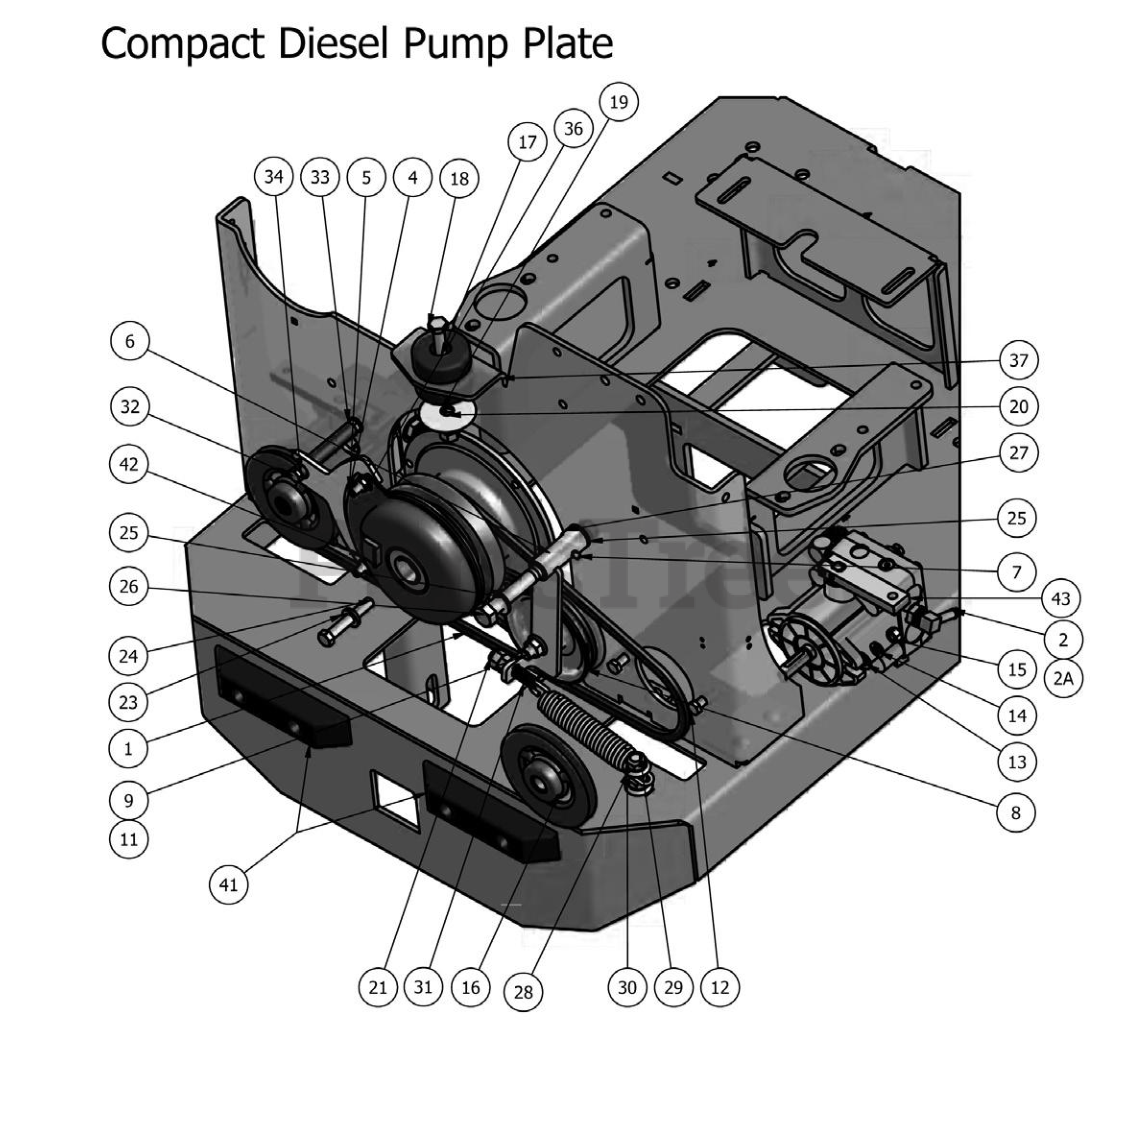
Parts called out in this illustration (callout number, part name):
2	Hydraulic Pump with Fan and Cover Left
2A	Hydraulic Pump with Fan and Cover Right
3	Diesel Clutch
4	Diesel PTO Engager Holder
5	3/8" x 1 1/4" Carriage Bolt
6	Pump Idler Bracket (60 Only)
7	1/4" Drive-in Grease Fitting
8	4 3/4" Idler Pulley
9	1/2" x 2" Hex Bolt
10	5/8" x 1 1/8" Brass Bushing
11	1/2" Flange Nut
12	3/8" x 1 1/4" Hex Bolt
13	3/8" Flat Washer
14	3/8" Lock Washer
15	3/8" Hex Nut
16	5" Pump Pulley
17	Rubber Isolator
18	1/2" x 3" Bolt
19	1/2" Flat Washer
20	1/2" Lock Washer
21	1/2" Hex Nut
22	5/8" Nylock (1/2 Jam)
23	7/16" Lock Washer
24	7/16" x 2 3/4" Fine Thread Bolt
25	.635 ID Plastic Washer
26	5/8" x 4 1/2" Hex Bolt
27	1/2" Collar Spacer
28	6" Pump Idler Spring
29	1/2" x 2" Carriage Bolt
30	1/2" Nylon Flange Nut-Orange
31	1/2" x 2 1/2" All Thd Stud
32	3/8" x 4 1/2" Bolt
33	3/8" Flange Nut
34	Rubber Spacer
35	Stub Shaft
36	3/8" Nylock Flange Nut
37	Pump Plate Diesel
38	5" Idler Pulley
39	5/8" x 5 1/2" Hex Bolt
40	Clutch Pigtail
41	8" Rubber Bumper
42	5/8" Set Collar
